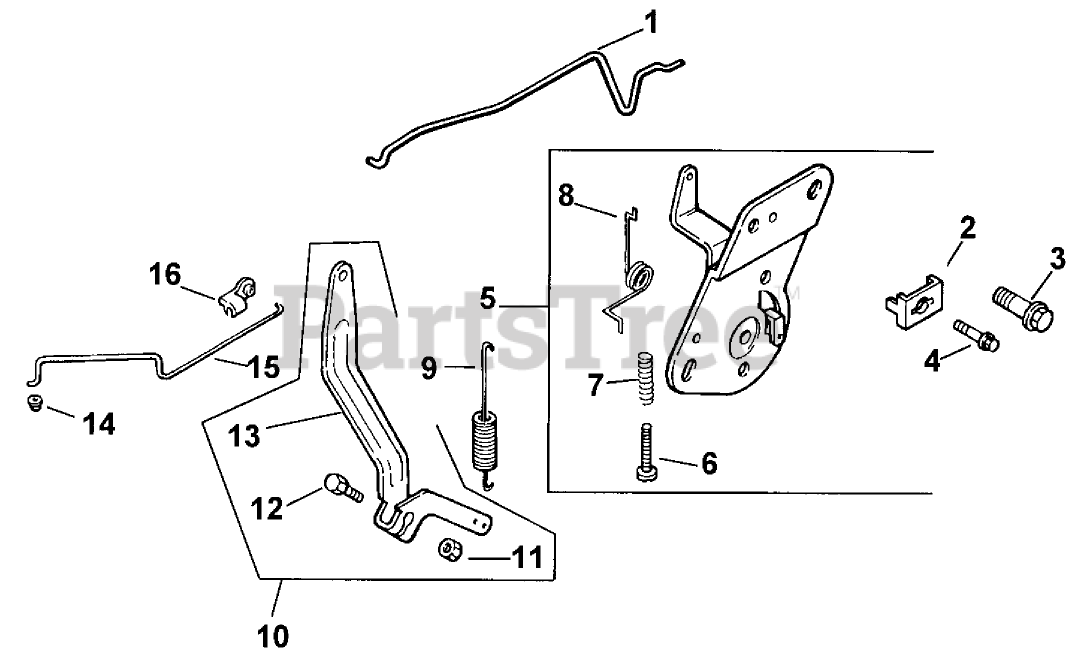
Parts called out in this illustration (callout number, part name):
1	Linkage Choke
2	Clamp
3	Screw Socket
4	Screw
5	Control-Speed
6	Screw
7	Spring
8	Spring Choke
9	Spring-Governor
10	Kit-Governor Lever (Incl. Ref.#11-13)
11	Nut
12	Bolt
13	Lever-Governor
14	Bushing-Linkage
15	Linkage-Throttle
16	Bushing-Linkage
